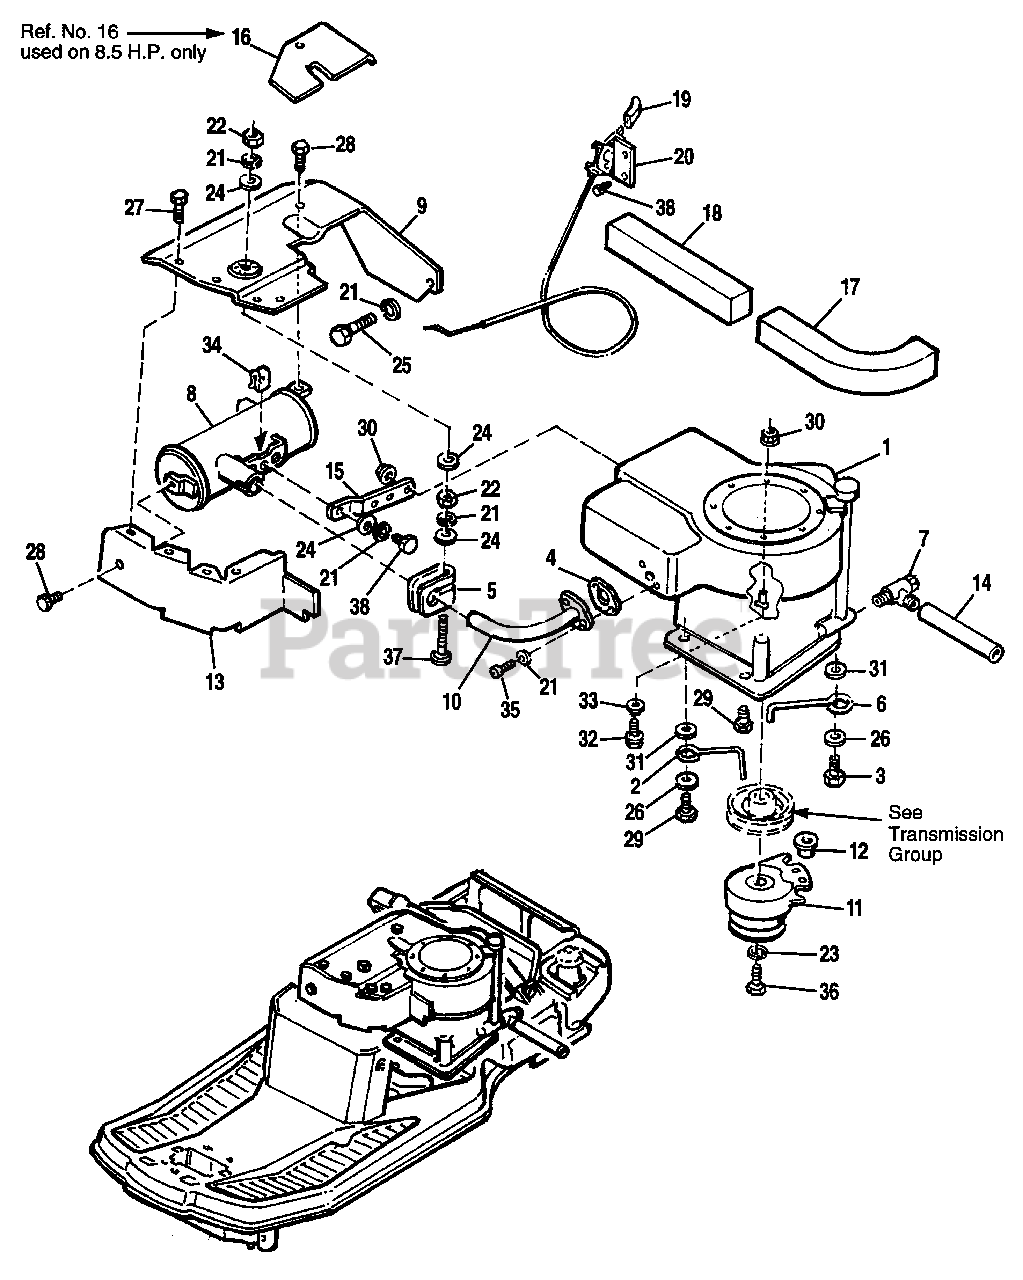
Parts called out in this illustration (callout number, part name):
1	ENGINE, 8.5,10 & 12 HP (Briggs & Stratton)
3	SCREW, Hex, Washer Hd., Taptite, 3/8-16 x 2
4	GASKET, Muffler
5	CLAMP, Muffler
7	DRAIN VALVE, Oil
8	MUFFLER ASSY.
9	DUCT, Top, RH
10	PIPE, Exhaust
11	ELECTRIC CLUTCH
12	SLEEVE, Clutch Anchor
13	DUCT, Top, LH
14	HOSE, Oil Drain
15	SUPPORT, Muffler
16	DUCT, Top, Muffler, 8.5 HP
17	SEAL, Air Inlet
18	SEAL, Air Inlet
19	KNOB, Throttle Control
20	THROTTLE CONTROL ASSY.
21	LOCKWASHER, 5/16
22	NUT, Hex, 5/16-18
23	LOCKWASHER, 7/16
24	WASHER, 11/32
25	CAPSCREW, Hex Hd., 5/16-18 x 3/4
26	WASHER, Plain, 3/8
27	SCREW, Hex Hd., 10-16 x 3/8
28	SCREW, Hex, Flange, Taptite, 5/16-18 x 1/2
29	SCREW, Taptite, 3/8-16 x 1-1/2
30	NUT, Hex, Flange, Whizlock, 5/16-18
31	WASHER, Plain
32	SCREW, Hex, Flange, Whizlock, 5/16-18 x 1-1/2
33	PUSH NUT
34	NUT, Speed, 5/16-18
35	CAPSCREW, Socket Hd., 5/16-18 x 3/4
36	CAPSCREW, Hex Hd., 7/16-20 x 2-1/2
37	CARRIAGE BOLT, 5/16-3 x 1-1/4
38	SCREW, Hex, Taptite 1/4-20 x 1/2
